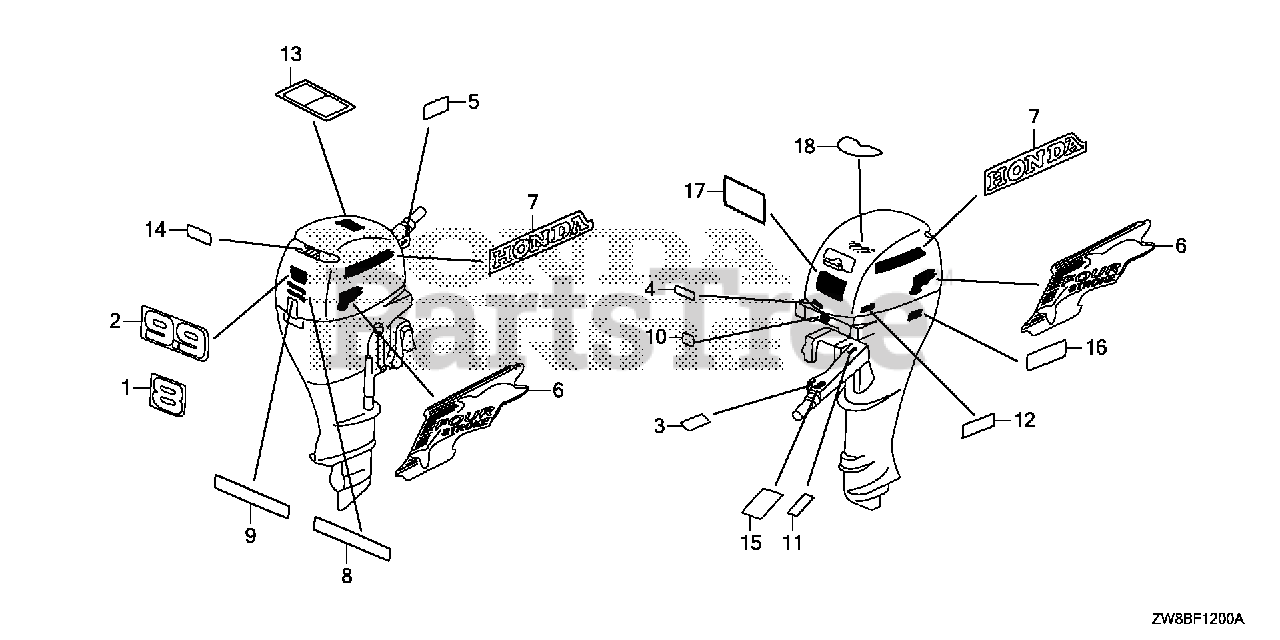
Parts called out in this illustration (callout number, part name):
1	MARK, RR. (8)
3	MARK, EMERGENCY SWITCH INDICATION (EU)
4	MARK, SPARE CLIP (ENGLISH)
5	MARK, STARTER (ENGLISH)
6	MARK, SIDE
7	MARK, SIDE STRIPE (HONDA)
8	MARK, POWER THRUST
10	MARK, OIL PRESSURE
11	MARK, CHANGE
14	LABEL, OIL CAUTION (ENGLISH)
15	MARK, THROTTLE (ENGLISH)
16	LABEL, STORING CAUTION (ENGLISH)
17	LABEL, WARNING OPERATOR (ENGLISH)
18	MARK, EMERGENCY STARTER (ENGLISH)
